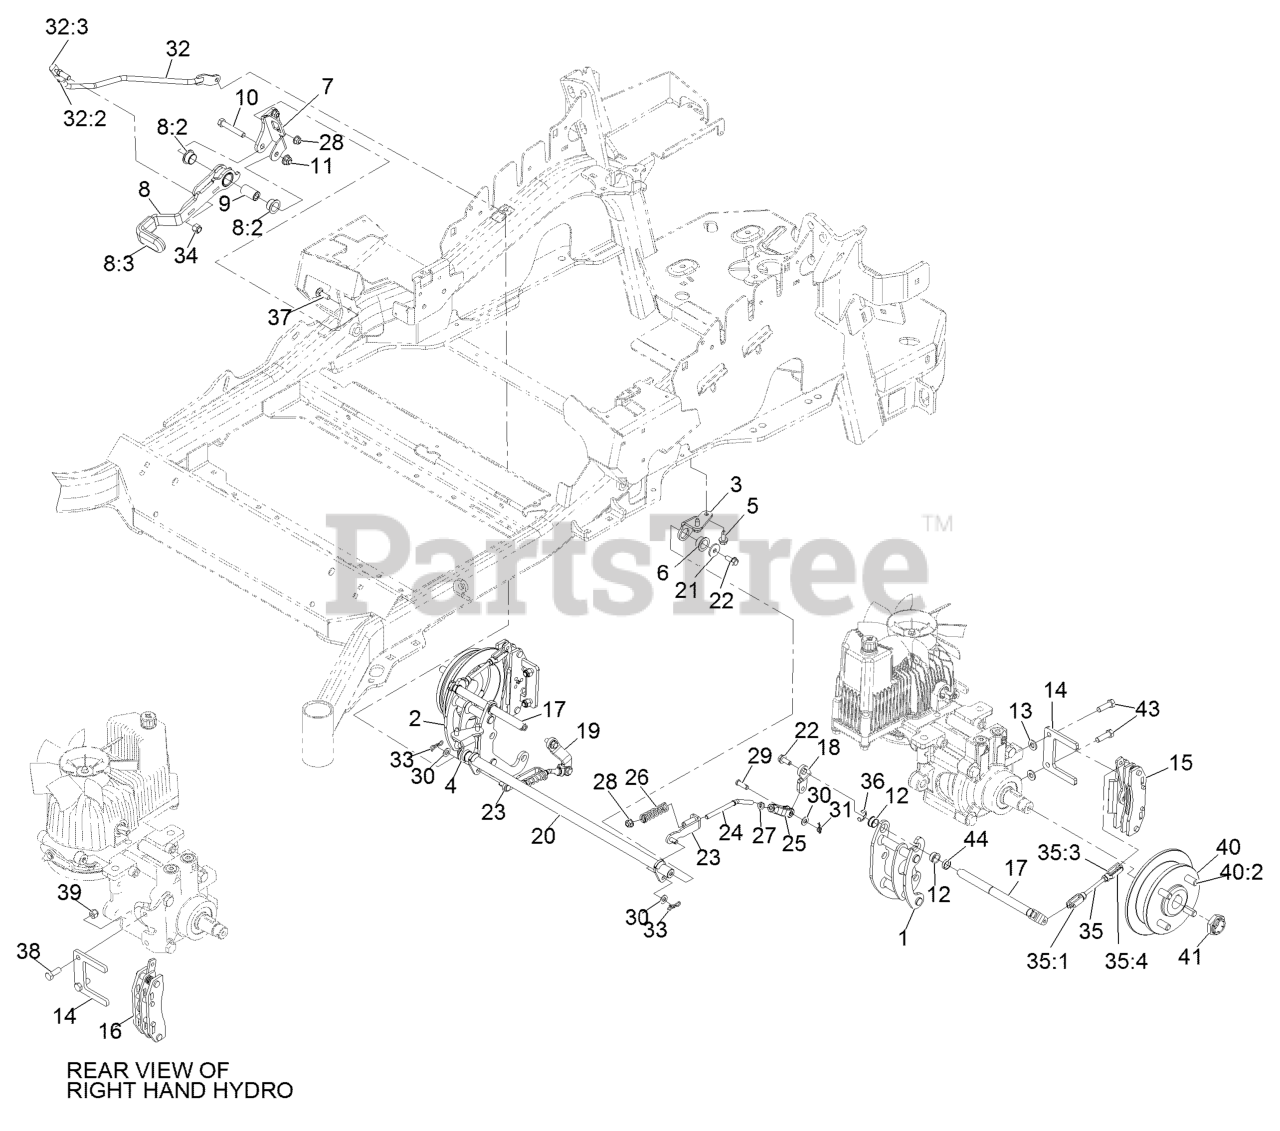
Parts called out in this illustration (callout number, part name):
1	MOUNT-BELLCRANK, LH
2	MOUNT-BELLCRANK, RH
3	MOUNT-PIVOT, LH
4	MOUNT-PIVOT, RH
5	Screw-HWH 5/16-18 X 3/4 Tf
6	BUSHING-FLANGE
7	BRACKET-MOUNT
8	BRAKE LEVER ASM
8:2	BUSHING-FLANGE
8:3	GRIP-LEVER
9	HANDLE-PIVOT, BRAKE
10	SCREW-HH
11	NUT-HF, NI
12	BUSHING
13	WASHER-FLAT
14	PLATE-MOUNT, BRAKE
15	CALIPER-BRAKE
16	CALIPER-BRAKE, RH
17	BELLCRANK
18	ARM-INNER, LH
19	ARM-INNER, RH
20	SHAFT-CROSS
21	WASHER-FLAT
22	SCREW-HHF
23	BRACKET-L
24	LINKAGE-MID
25	YOKE-OFFSET
26	SPRING-COMPRESSION
27	NUT-JAM
28	NUT-HF, NI
29	PIN-CLEVIS
30	WASHER-PLAIN
31	PIN-COTTER, LOCKING
32	FRONT LINKAGE ASM
32:2	END-TIE ROD, RH
32:3	NUT-HJ
33	PIN-COTTER, LOCKING
34	NUT-LOCK
35	REAR LINKAGE ASM
35:3	NUT-JAM
35:4	PIN-CLEVIS, SPRING
37	BOLT-CARR
38	SCREW-HH
39	NUT-LOCK, NI
40	WHEEL HUB ASM
40:2	STUD-WHEEL
41	LOCKNUT
43	SCREW-LOCK, PATCH
